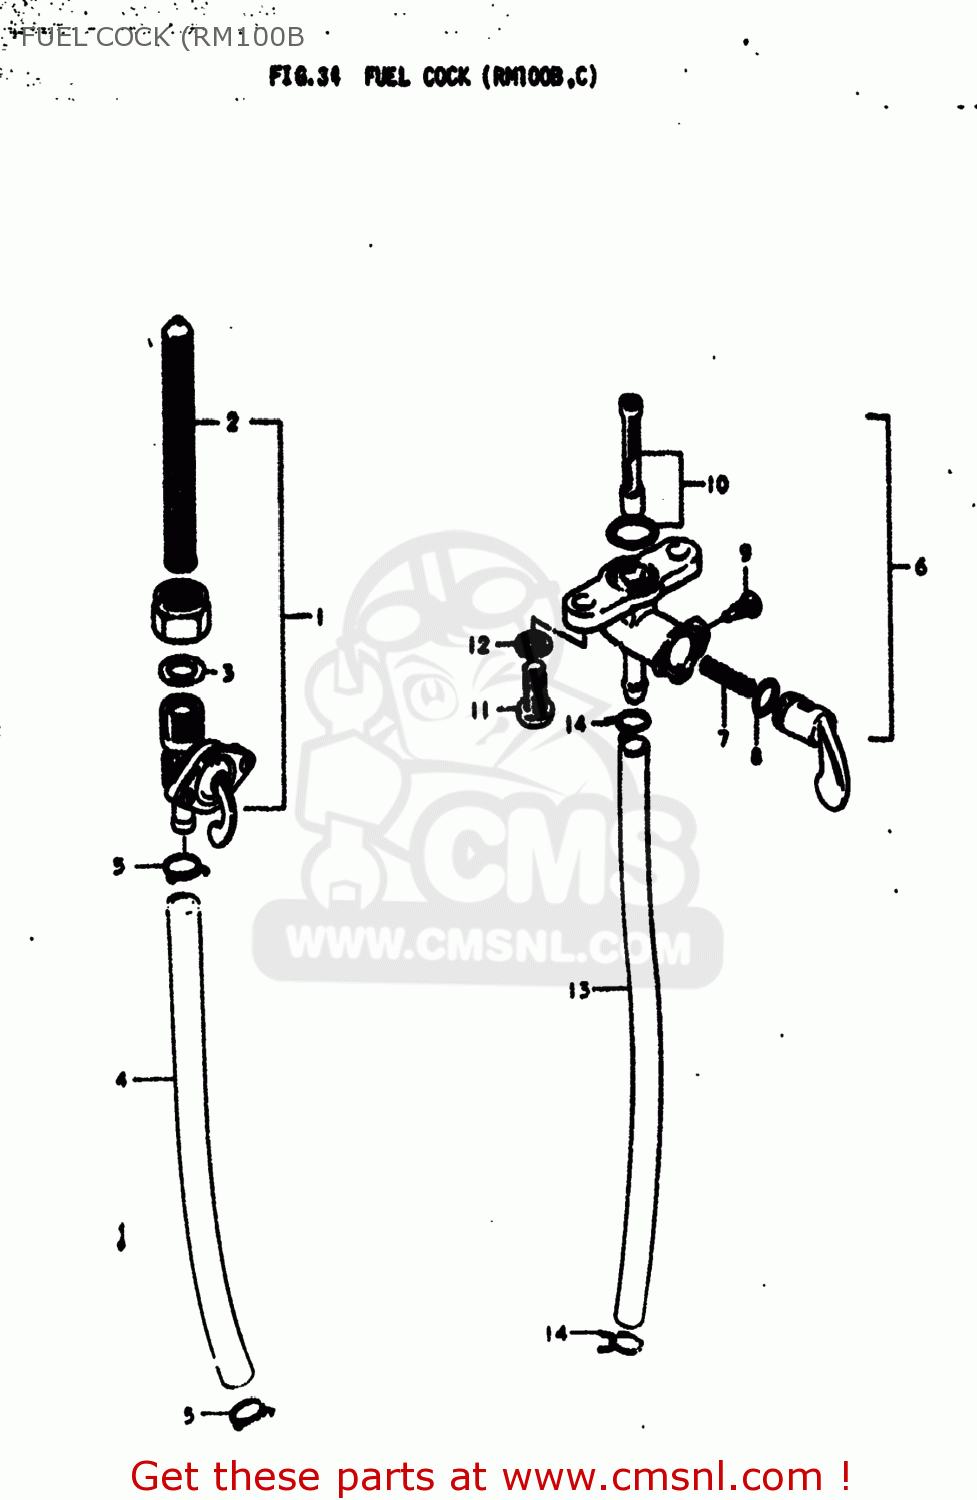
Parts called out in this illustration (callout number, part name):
1	COCK ASSY,FUEL
2	FILTER,FUEL
3	GASKET,FUEL COCK (NAS)
4	HOSE
5	CLIP
6	COCK ASSEMBLY,FUEL
7	SPRING,FUEL COCK VALUE
8	O RING,LEVER
9	SCREW
10	FILTER SET FUEL
11	SCREW
12	LOCK WASHER
13	HOSE
14	CLIP
